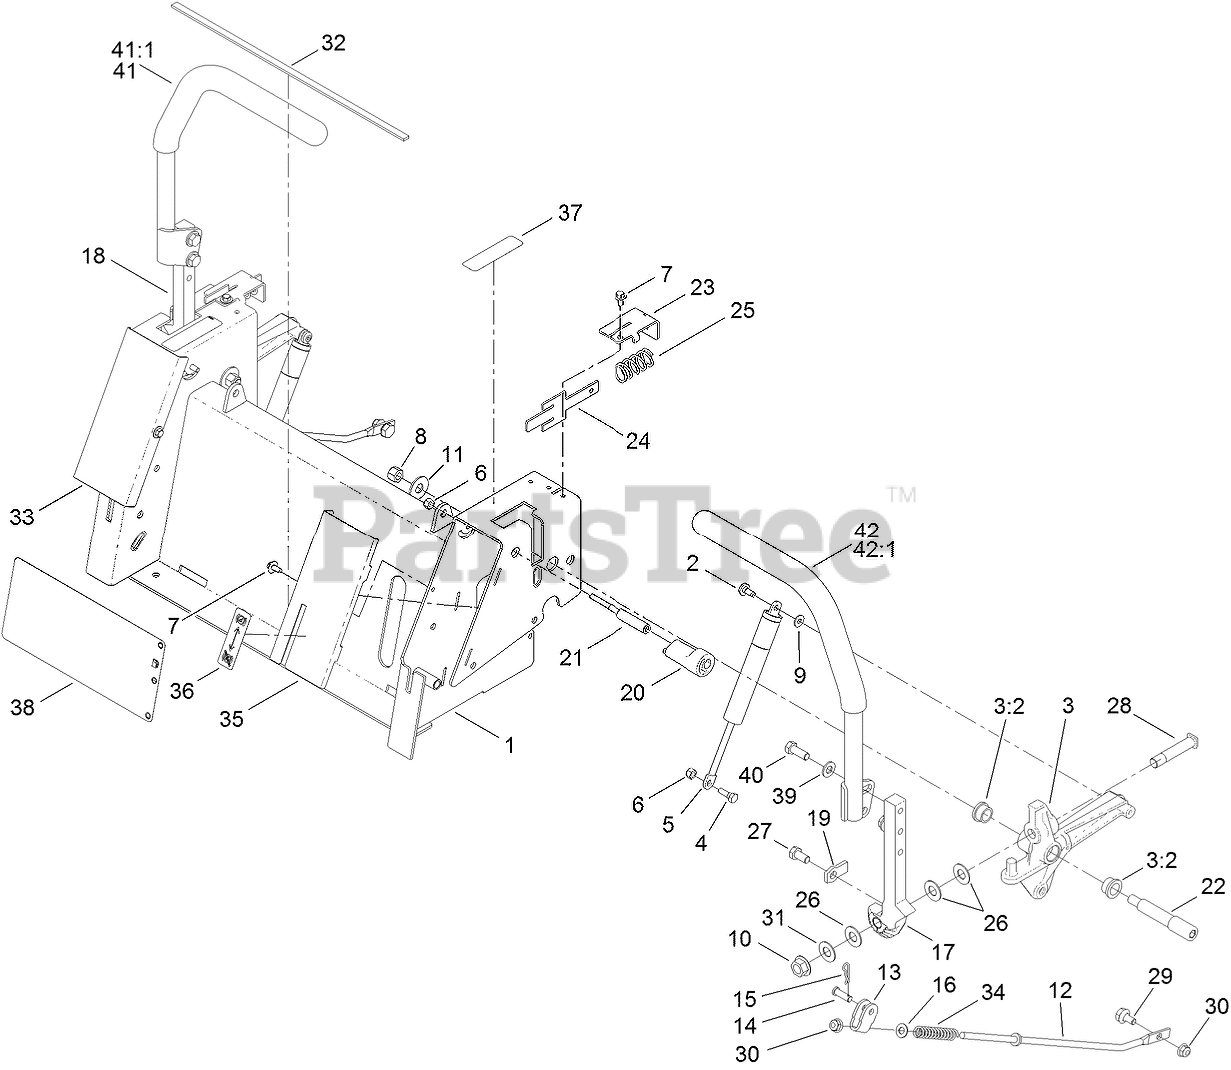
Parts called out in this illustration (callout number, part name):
1	BOX-CONTROL
2	SCREW-SHOULDER
3	ACTIVATOR ARM ASM
3:2	BUSHING
4	BOLT-SHOULDER
5	DAMPER-CONTROL, MOTION
6	NUT-LOCK, NI
7	SCREW-HHFTF
8	NUT-LOCK, NI
9	WASHER
10	NUT-HF
11	WASHER-FLAT
12	ROD-CONTROL
13	BRACKET-CONTROL
14	PIN-CLEVIS
15	PIN-COTTER
16	WASHER-PLAIN
17	ARM-ACTUATOR, LH
18	ARM-ACTUATOR, RH
19	TAB-STOP
20	ECCENTRIC
21	SCREW-ECCENTRIC
22	BOLT-SHOULDER
23	BRACKET-RETURN
24	PLATE-RETURN
25	SPRING-COMPRESSION
26	WASHER-PIVOT
27	SCREW-HH
28	BOLT-SHOULDER
29	BOLT-SHOULDER
30	NUT-HF, NI
31	WASHER-TEFLON
32	STRIP-VIBRATION, ANTI
33	COVER-CONTROL, RH
34	SPRING-RETURN, NEUTRAL
35	COVER-CONTROL, LH
36	DECAL-BRAKE, PARKING
37	DECAL-CONTROL, MOTION
39	WASHER-FLAT
40	SCREW-HH
41	RH LEVER/GRIP ASM
41:1	Grip-Control, Motion
42	LH LEVER/GRIP ASM
42:1	Grip-Control, Motion
